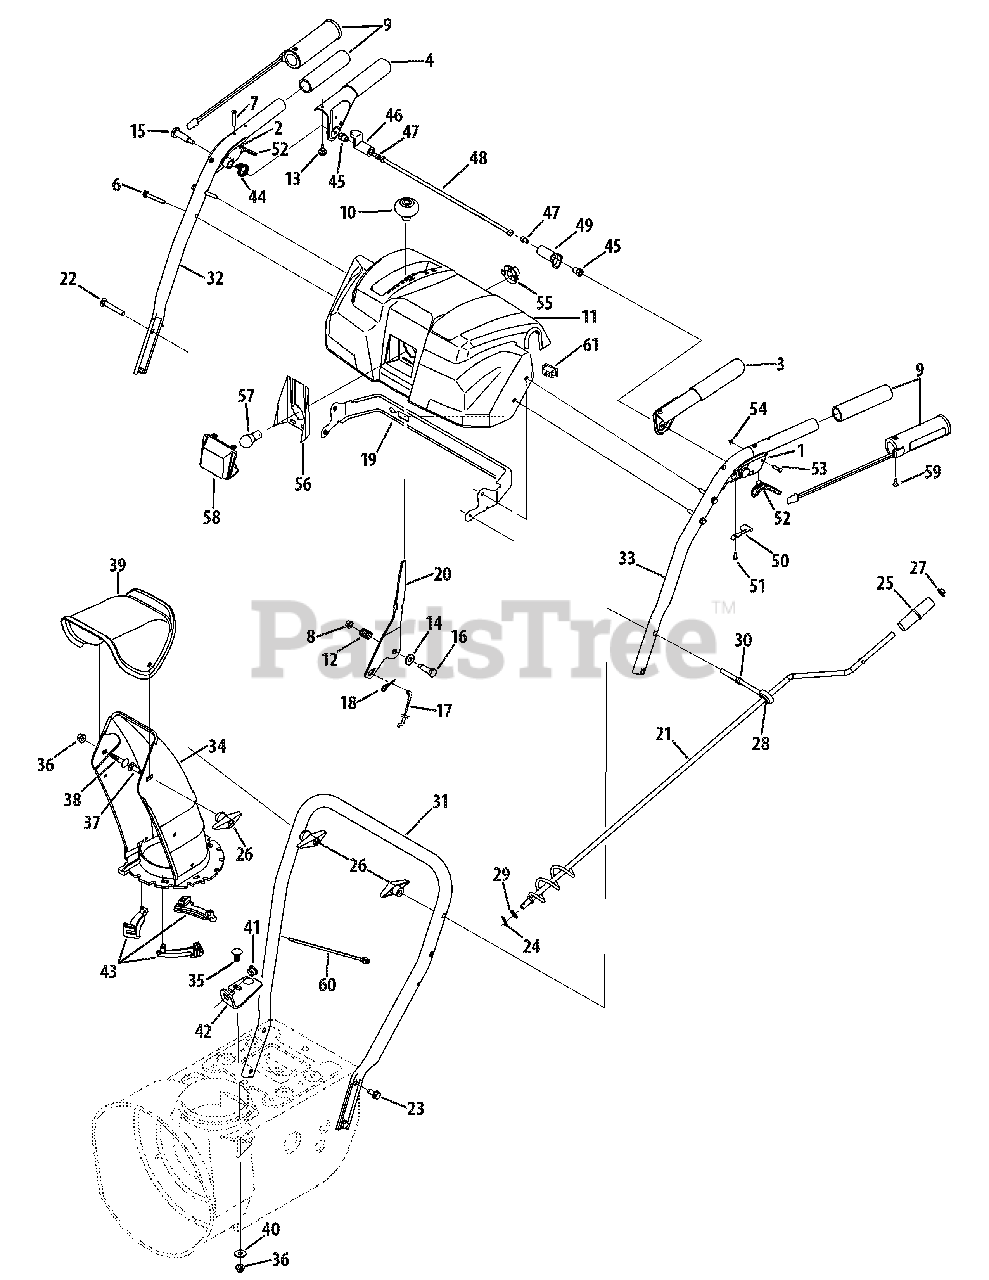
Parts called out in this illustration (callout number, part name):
1	Handle Assembly Lock LH
2	Handle Assembly Lock RH
3	Hande Assembly, Engagement LH
4	Handle Assembly Engagement RH
5	Wire Harness w/ Htd Grips (NS)
6	Screw, 1/4-20, 1.625
7	Machine Screw, #10-24, 1.375
8	Flange Lock Nut,, 1/4-20
9	Heated Grip
10	Shift Knob
11	N-Style Panel (w/o cutout)
11	N-Style Panel (w.cutout)
12	Spring, .39 x .60 x.88
13	Rubber Bumper, .62 OD x .22
14	Flat Washer, .385 x .87 x .06
15	Shoulder Screw, .43 x 1.34, 1/4-20
16	Shoulder Screw, .374 Dia x 1.05
17	Speed Selector Cable
18	Click Pin
22	Carriage Screw, 5/16-18, 2.25
23	Hex Scerw, 5/16-18 x .750
24	Cotter Pin
25	Crank Knob, 1.0 Dia x 3.2
26	Wing, Knob
27	Push Cap, 3/8 Rod
28	Grommet, .44ID x .94 OD x .50
29	Flat Washer, .375 x .738 x .063
30	Chute Crank Eye Bolt
34	Lower Chute
35	Carriage Bolt, 5/16-18, 1.0
36	Flange Lock Nut, 5/16-18, Nylon
37	Carriage Bolt, 5/16-18, 1.0
38	Carriage Bolt, 5/16-18, .750
39	Upper Chute w/Label
40	Washer, .349 ID x .879 OD x .063
41	Plastic Bushing, .380
43	Chute Flange Keeper
44	Torsion Spring
45	Shoulder Nut
46	Lock Plate
47	Cap Screw, 1/4-20 x .375
48	Pivot Rod
49	Clutch Lock Cam
50	Clutch Lock Spring
51	Screw, #8-16 x .50
52	Steering Triggers
55	Light Socket
56	Lens Reflector Label
57	Bulb
58	Lens Reflector Label
60	Cable Tie
61	Heated Grip Switch
